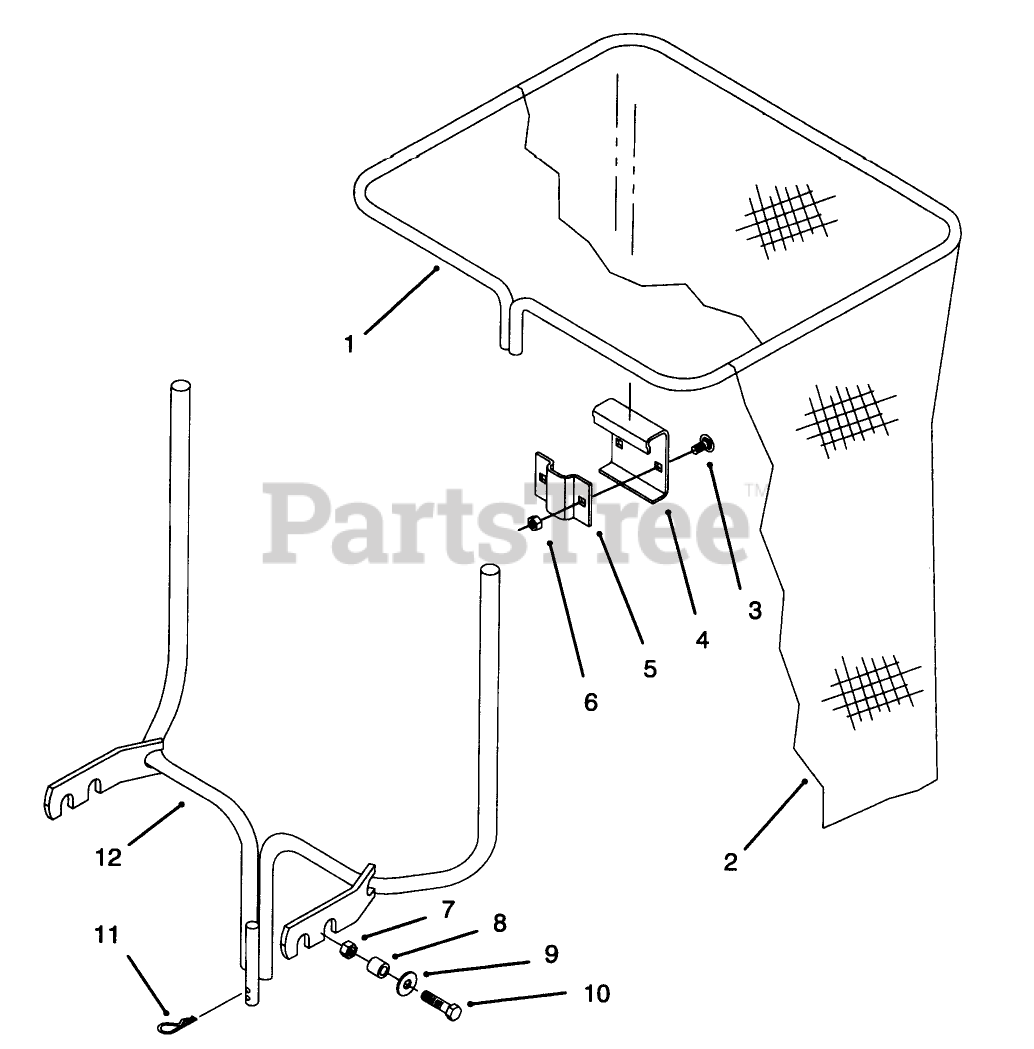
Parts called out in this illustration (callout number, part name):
2	BAG-DEPTH
3	BOLT-CARR
6	NUT-LOCK, NI
7	NUT-LOCK, NI
8	SPACER
10	SCREW-HH
11	PIN-COTTER, HAIR
